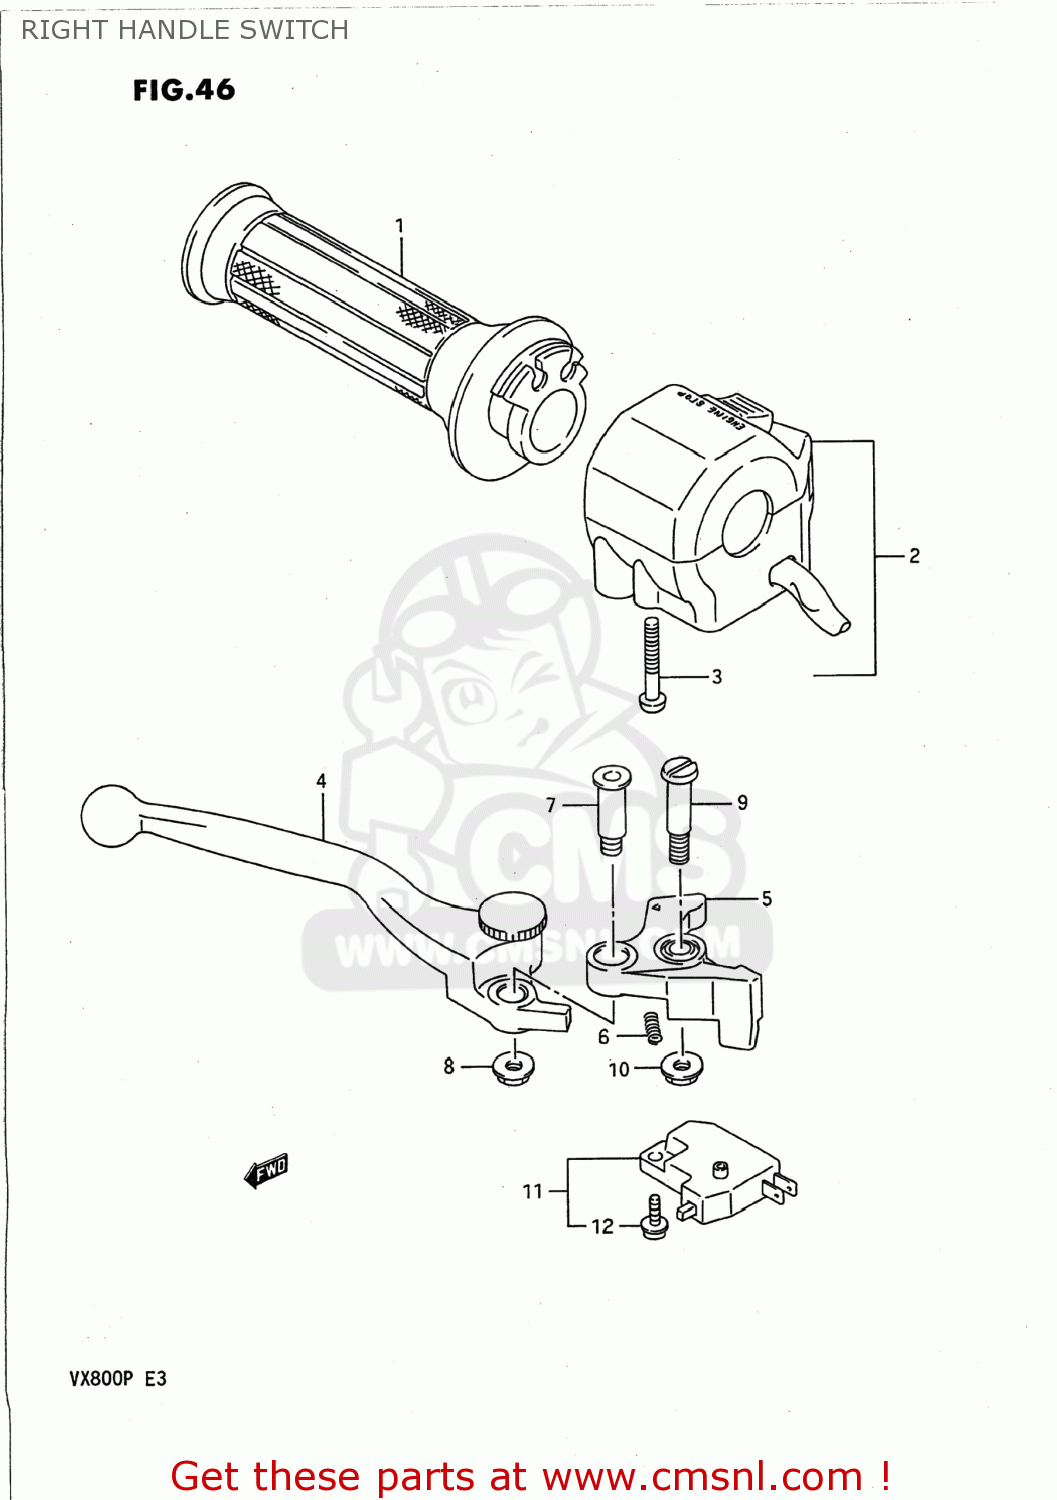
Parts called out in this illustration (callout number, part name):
1	GRIP,THROTTLE
2	SWITCH ASSEMBLY,HANDLE,RIGHT
3	SCREW, 5X45
4	LEVER,ADJUST
5	KNOCKER
6	SPRING
7	BOLT,LEVER
8	NUT
9	BOLT,LEVER PIVOT
10	NUT 6MM
11	SWITCH ASSEMBLY,STOP
12	SCREW
